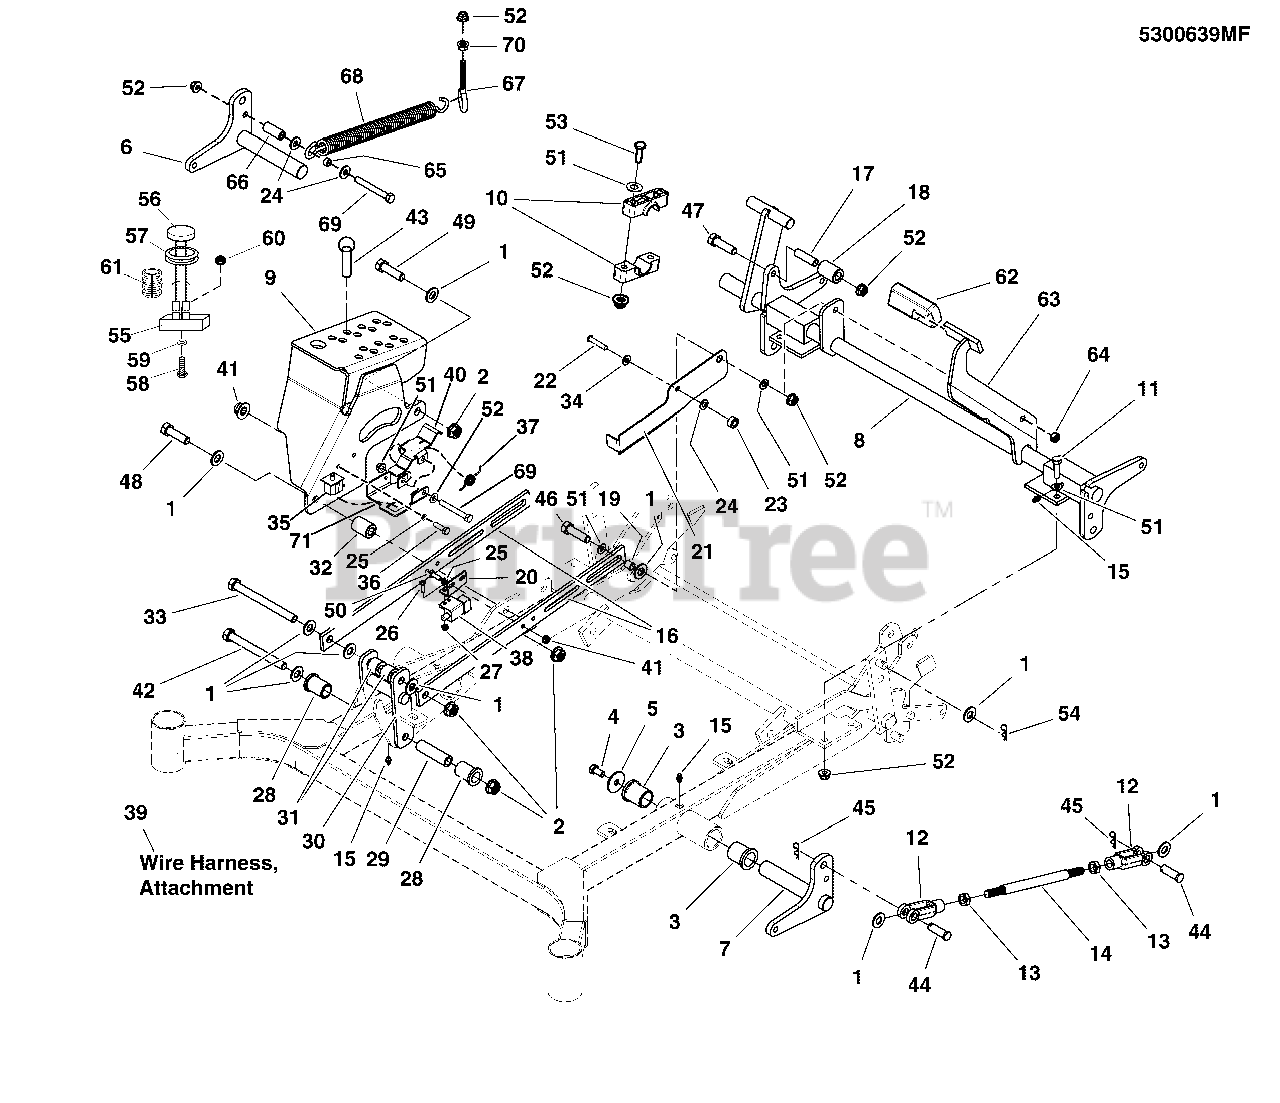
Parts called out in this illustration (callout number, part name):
1	WASHER, 1/2 SAE
2	NUT, 1/2-13 HEX NYLOCK FLANGE
3	BUSHING, FLANGE
4	BOLT, 3/8-16 X 3/4, GD5, YZ WITH PATCH
5	WASHER, .390 X 1.50 X .109, YZ
6	WELD., DECK LIFT LEVER - RH - RED
7	WELD., DECK LIFT LEVER - LH - RED
8	WELD, DECK LIFT SHAFT - OUTFRONT - RED
9	WELD, CUT HEIGHT BOX - RED
10	PIVOT BLOCK, PLASTIC
11	BOLT, 3/8-16 X 1-1/4 GD5
12	CLEVIS, 1/2-20, STEEL
13	NUT, 1/2-20 HEX JAM
14	ROD, DECK LIFT, OUTFRONT
15	GREASE FITTING, 1/4-28 STRAIGHT
16	BAR, ACTUATOR LINK - RED
17	SPACER, .38 X .50 X 1.78 YZ
18	SPACER, .51 X 1.00 X 1.47 YZ
19	SPACER, .38 X .50 X .50, YZ
20	PLATE, SWITCH MOUNT - RED
21	PLATE, SWITCH COVER - RED
22	PIN-CLEVIS, 5/16 X 1 YZ
23	COLLAR, 5/16 SET
24	WASHER, 5/16 USS
25	WASHER, 1/4 SAE
26	SCREW, #10-24 X 3/4 ROUND PHILLIPS
27	NUT, #10-24 HEX NYLON LOCK
28	BUSHING, FLANGED, 3/4 X 1 X 1
29	SPACER, .51 X .75 X 2.66
30	WELD, PIVOT LINK - ACTUATOR - RED
31	SPACER, .52 X 1.00 X .75
32	SPACER, .52 X 1.00 X 1.38 YZ
33	BOLT-1/2-13 X 5 GD5 YZ
34	WASHER, 5/16 SAE
35	SWITCH, LOWER PRO, NC/NC
36	BOLT, 1/4-20 X 1", GD
37	SPRING, TORSION, .591ID X .40LG X .095WR
38	SWITCH, PLUNGER, N.O./N.C.
39	WIRE HARNESS, ATTACHMENT, DECK
40	INDICATOR, DECK POSITION - BLK
41	NUT, 1/4-20 HEX NYLOCK FLANGE
42	BOLT, 1/2-13 X 4 GD5 YZ
43	PIN-COTTERLESS
44	CLEVIS PIN, 1/2 X 1.36 SAE STANDARD
45	PIN, COTTER, 3/32X.75
46	BOLT, 3/8-16 X 1-1/2 GD5 YZ
47	BOLT, 3/8-16 X 2-3/4 GD5 YZ
48	BOLT, 1/2-13 X 2-3/4 GD5
49	BOLT, 1/2-13 X 1-1/2 GD5 YZ
50	BOLT, 1/4-20 X 3/4 GD5 YZ
51	WASHER, 3/8 SAE
52	NUT, 3/8-16 HEX NYLOCK FLANGE
53	BOLT, 3/8-16 X 2-1/2 GD5 YZ
54	PIN, HAIR, .0915 X 1-7/8
55	FLASHER, 90 FPM, OUT FRONT MOWER
56	INDICATOR LAMP, RED, LED
57	GROMMET, 1/2
58	BOLT, 1/4-20 X 1-1/2, GD5
59	WASHER, 1/4 SAE
60	NUT, 1/4-20 HEX NYLOCK FLANGE
61	WIRE LOOM, 3/8 ID X 7" LONG
62	RUBBER, FOOT PEDAL
63	WELD, QUICK DECK LIFT PEDAL - RED
64	NUT, 3/8-16 HEX SIDE LOCK
65	SPACER, .38 X .50 X .27
66	SPACER, .39 X .63 X 1.50
67	EYEBOLT, 3/8-16 X 4, 2-1/8 OF THREAD
68	SPRING, DECK LIFT ASSIST
69	BOLT, 3/8-16 X 3 GD5 YZ
70	NUT, 3/8-16 HEX SERRATED FLANGE
71	WELD, SWITCH MOUNT - BLK
